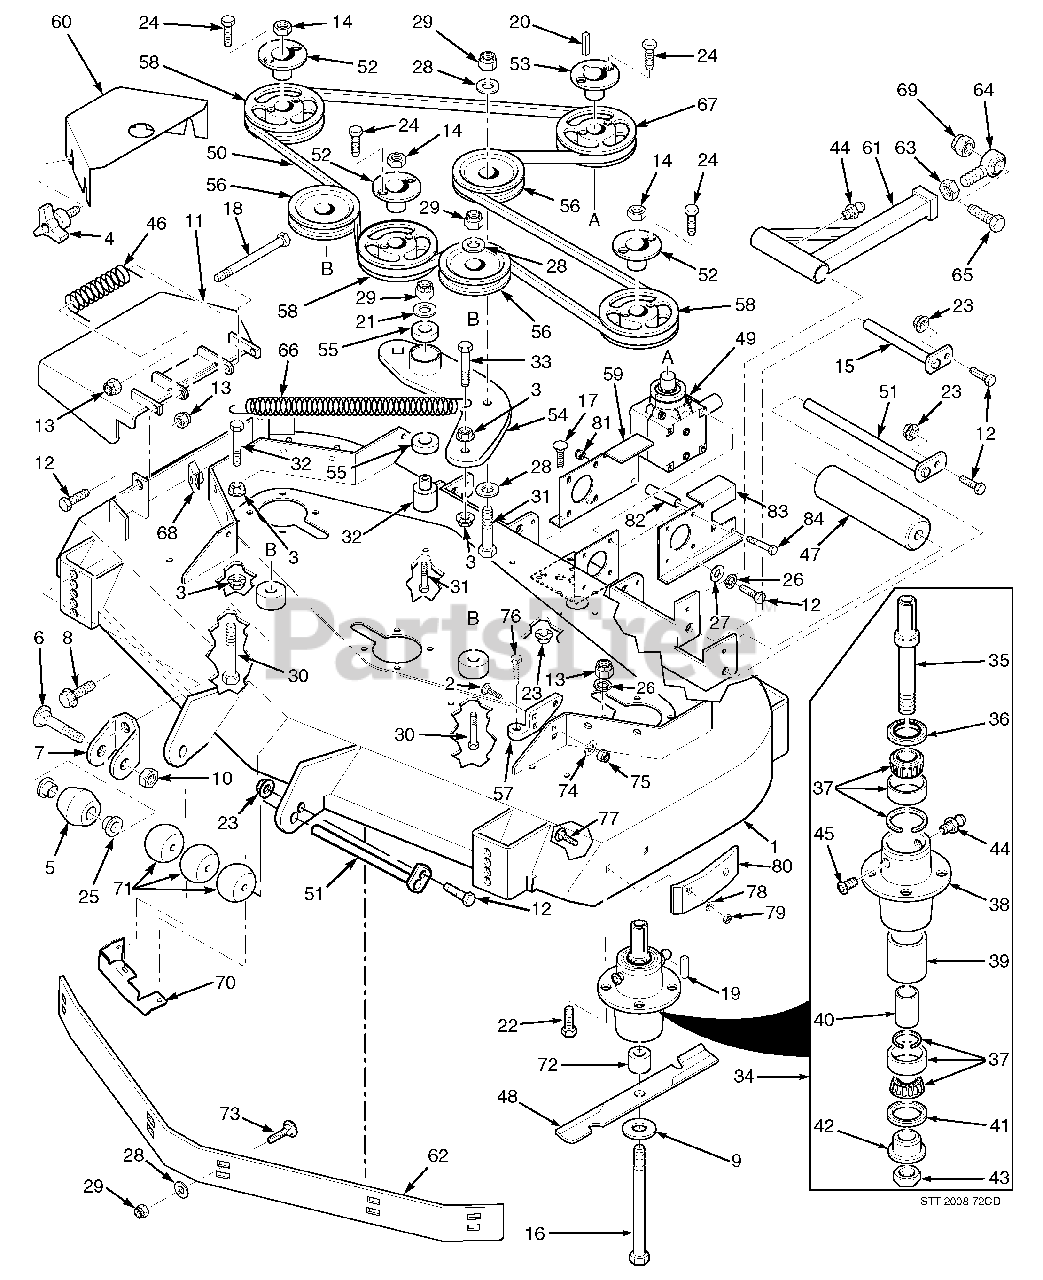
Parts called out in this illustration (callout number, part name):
1	Cutter Deck, 72" Advantage w/Decals
2	Bolt, Carriage 7/16-14 x 1-1/4"
3	Nut, Hex Serrated Flange 3/8-16
4	Wing Nut, 3/8-16
5	Anti-Scalp Wheel
6	Bolt, Carriage 3/8-16 x 4"
7	Anti-Scalp Wheel Bracket
8	Bolt, Hex Serrated Flange 3/8-16 x 1"
9	Flatwasher, 5/8" Hardened
10	Locknut, 3/8-16 Center Lock
11	Discharge Chute, 72" Adv.
12	Bolt, Hex Head 5/16-18 x 1.75" - Front
13	Nut, Hex Elastic Stop 5/16-18 Grade
14	Nut, 5/8-11 UNC
15	Push Arm Shaft
16	Bolt, Hex Head 5/8-11 x 9.50"
17	Bolt, Carriage 5/16-18 x .75"
18	Bolt, Hex Head 5/16-18 x 4.75"
19	Key, 1/4 x 1/4 x 2"
20	Key, 1/4 x 1/4 x 1.25"
21	Flatwasher,3/8" (.39 x .938 x .105") HD
22	Bolt, Hex Head 5/16-18 x 1-3/4"
23	Nut, Hex Serrated Flange 5/16-18
24	Bolt, Hex Head 1/4-20 x 1" Grade 8
25	Bushing, .376" I.D. Oilite
26	Lockwasher, 5/16"
27	Flatwasher, 5/16" (.375 x .875 x .083")
28	Flatwasher, 3/8" (.391 x .938 x .105")
29	Nut, Hex Elastic Stop 3/8-16
30	Bolt, Hex Head 3/8-16 x 3-1/4"
31	Bolt, Hex Head 3/8-16 x 3"
32	Pivot, Idler - Short
33	Bolt, Hex Head 3/8-16 x 1.50" Grade 8
34	Spindle Assembly
35	Spindle Shaft
36	Seal, Top
37	Bearing Assembly
38	Spindle Housing
39	Spacer, Outside
40	Spacer, Inside
41	Seal, Bottom
42	Spindle Bushing, Bottom
43	Nut, Special 1-1/16-18
44	Grease Fitting
45	Relief Fitting, Tapered Spindle
46	Spring, Discharge Chute
47	Guide, Roller
48	Cutter Blade, 24.5"
49	Gearbox Assembly, Deck Drive
50	Belt, Cutter Deck Drive, 72"
51	Roller Shaft
52	Tapered Hub, 1-1/8" Bore
53	Tapered Hub, 1" Bore
54	Idler Arm, Cutter Deck
55	Bearings, Ball
56	Pulley, Idler
57	Lever Assembly, Deck Level
58	Pulley, 6.95" O.D. - 72"
59	Mounting Plate, RH Gearbox
60	Belt Cover, LH - 72"
61	Pusharm
62	Baffle, Custom Cut 72A
63	Nut, Hex Head 5/8-18 UNF
64	Rod End, 5/8" Male RH Thread
65	Bolt, Hex Head 5/8-11 x 4-1/2"
66	Spring, Cutter Deck
67	Pulley, 6.35" O.D. - 72"
68	U-Nut, 3/8-16
69	Nut, Hex Elastic Stop 5/8-11
70	Discharge Baffle 72"
71	Wheel, Anti-Scalp
72	Spacer, Spindle Bottom
73	Bolt, Carriage 3/8-16 x 1"
74	Flatwasher, 7/16" (.50 x 1.25 x .083")
75	Nut, Elastic Stop 7/16-14
76	Bolt, Deck Adjust
77	Bolt, Carraige 5/16-18 x 3/4"
78	Flatwasher, 5/16"
79	Nut, Center Lock 5/16-18
80	Wear Pad
81	Nut, Elastic Stop 5/16-18
82	Spacer, Gearbox Mount
83	Mounting Plate, LH Gearbox
84	Bolt, Hex Head 5/16-18 x 4-3/4"
